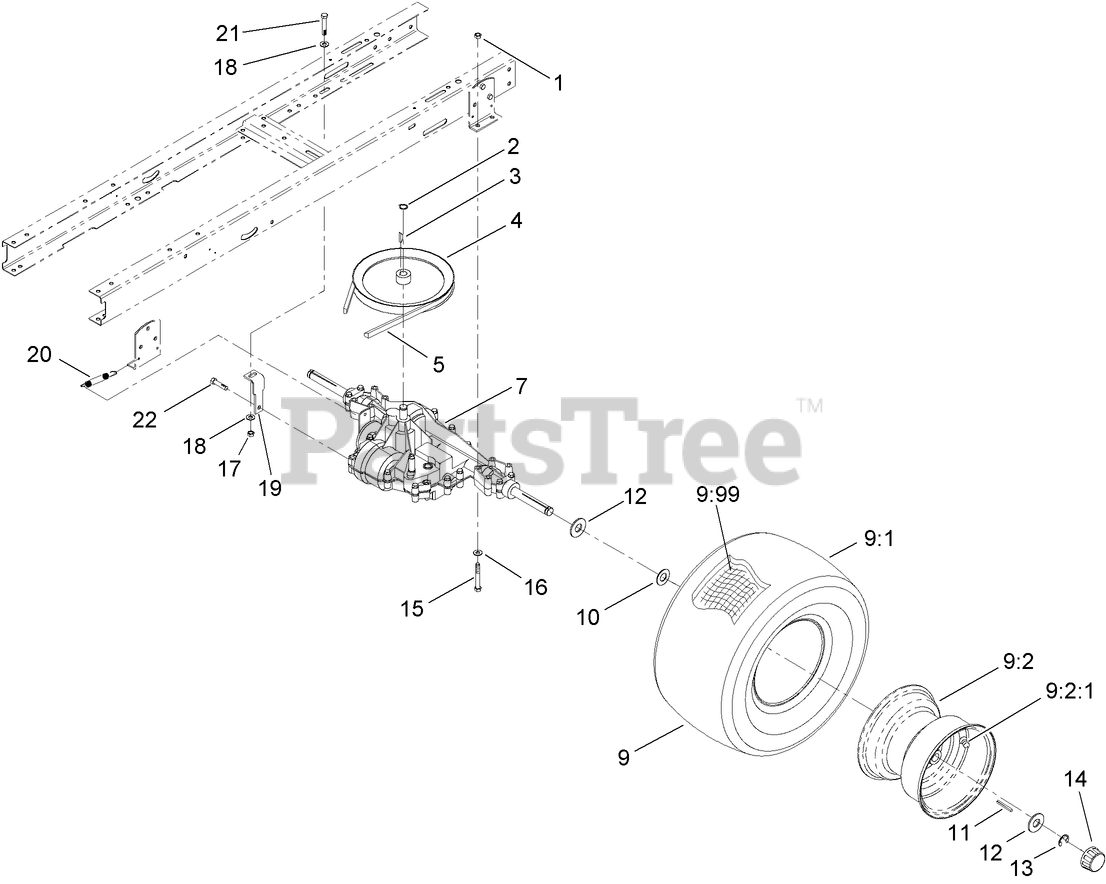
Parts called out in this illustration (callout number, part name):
1	NUT-LOCK, NI
2	RING-SNAP, EXTERNAL
3	KEY-WOODRUFF
4	PULLEY-TRANSMISSION
5	V BELT-TRACTION
7	TRANSAXLE ASM
9	Loose Parts Package
9:2	RIM ASM
10	WASHER-THRUST
11	KEY-SQUARE
12	WASHER-PLAIN
13	E-RING
14	CAP-HUB
15	SCREW-HH
16	WASHER-PLAIN
17	NUT-LOCK, NI
18	WASHER-PLAIN
19	STRAP-TORQUE
20	SPRING-RETURN, BRAKE
21	SCREW-HH
22	SCREW-HWHTF
